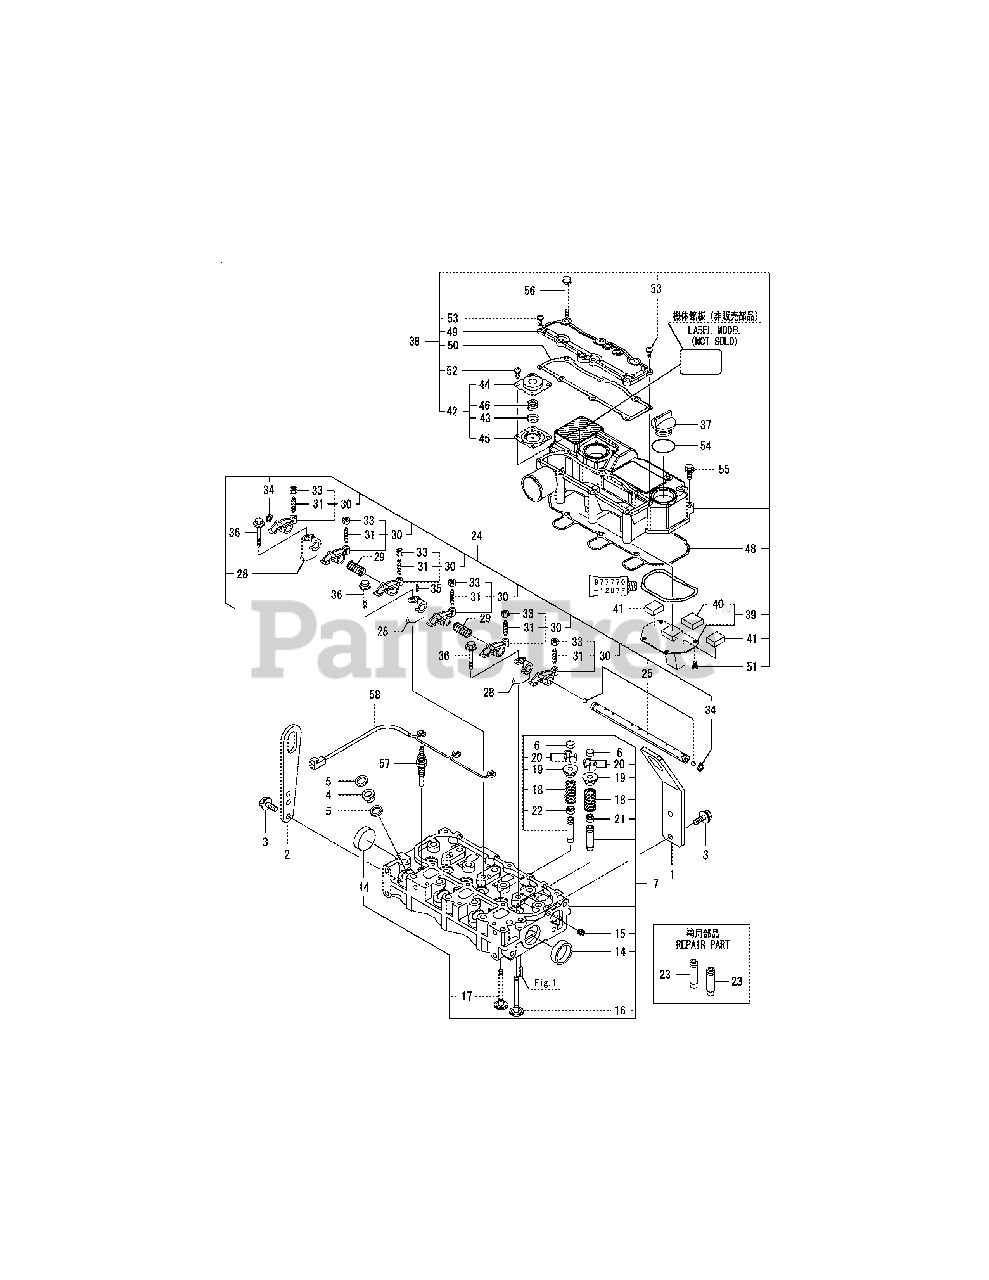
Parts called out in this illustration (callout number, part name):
1	LIFTER, ENGINE
2	LIFTER, ENGINE
3	BOLT M 8X 16 PLATED
4	PROTECTOR, NOZZLE
5	GASKET, NOZZLE
7	HEAD ASSY, CYLINDER
17	VALVE, EXHAUST
19	RETAINER, SPRING
21	SEAL, VALVE STEM
22	SEAL, VALVE STEM
24	SUPPORT ASSY, ARM
25	SHAFT ASSY, ROCKER
28	SUPPORT, ROCKER ARM
30	ARM ASSY, ROCKER
31	SCREW, VALVE ADJUST
36	BOLT M 8X 40 PLATED
38	BONNET ASSY, HEAD
40	BAFFLE, BREATHER
41	BAFFLE, BREATHER
42	DIAPHRAGM ASSY
44	COVER, DIAPHRAGM
46	SPRING, DIAPHRAGM
48	GASKET, BONNET
50	GASKET, BONNET COVER
54	O-RING 1A P-32.0
55	BOLT M 6X 20 PLATED
56	BOLT M 6X 75 PLATED
58	CONNECTOR, GLOW PLUG
